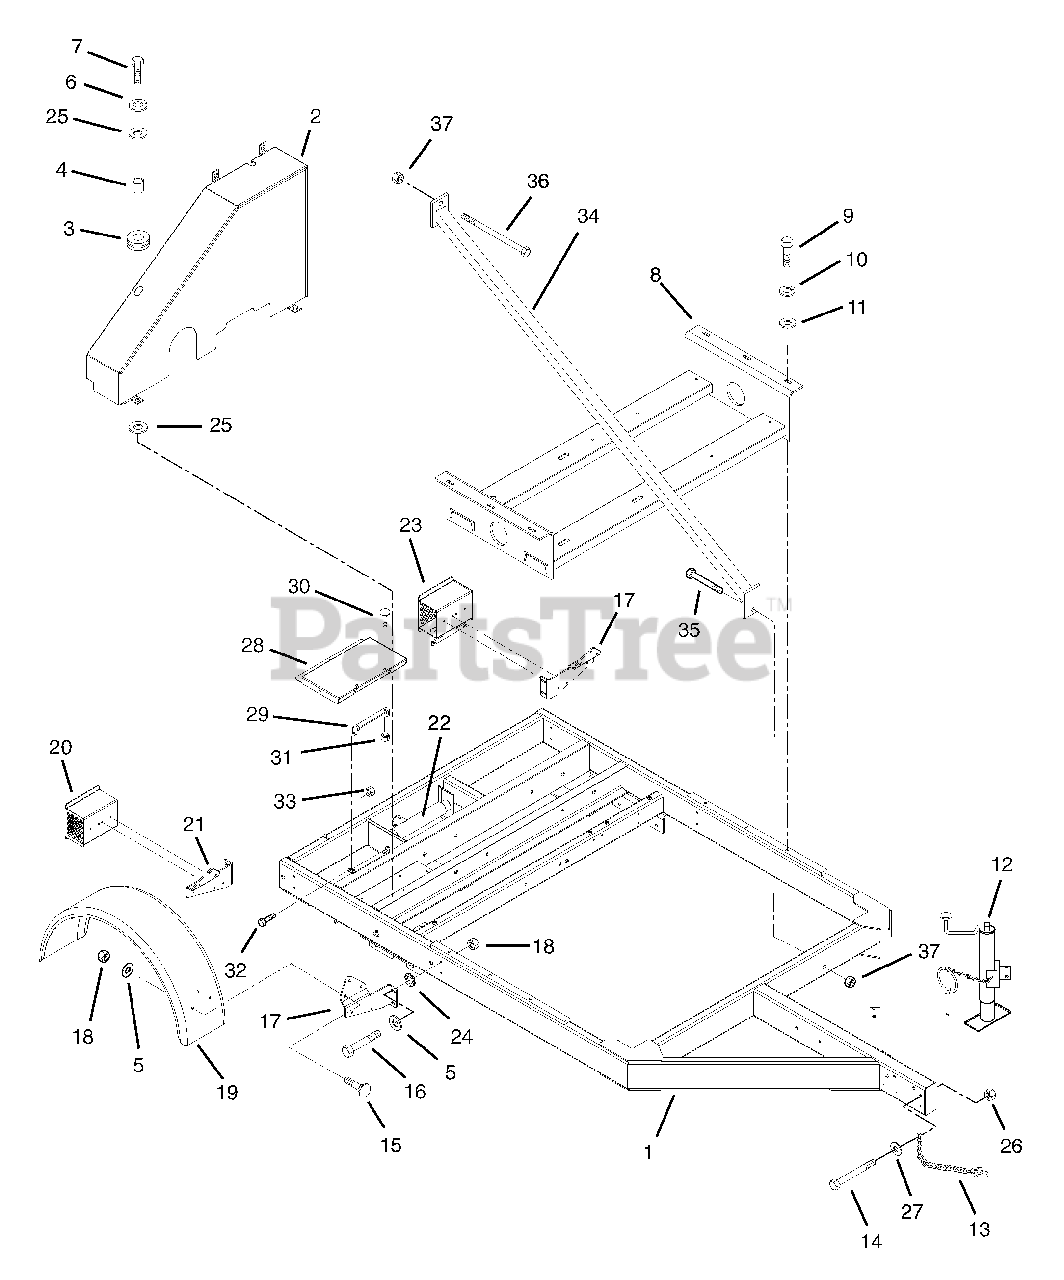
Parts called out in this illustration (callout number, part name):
1	Frame Weldment
2	Weldment-Belt Guard
3	Grommet .188 x .500
5	Washer-Flat-Steel .38 x .875 x .083
6	Washer-Lock .38 x .094
7	Bolt-Hex .38-16 x 1.25 Grade 5
8	Engine Base Weldment
9	Bolt-Hex .50-13 x 1.25 Grade 5
10	Washer-Lock .50 x .125
11	Washer-Flat-Steel .563 x 1.38 x .109
13	Safety Chain
14	Bolt-Hex .44-14 x 5.00 Grade 5
15	Bolt-Round Head Square Neck .31-18 x .75
16	Bolt-Hex .31-18 x 2.75 Grade 5
17	Fender Bracket-Left Hand
18	Nut-Locking-Center .31-18
19	Fender
20	Tail Light Bracket Weldment
21	Fender Bracket Right Hand
23	Left Hand Tail Light Bracket Weldment
24	Washer-Locking-External .326 x .599 x .031
25	Washer-Flat-Steel .39 x 1.5 x .125
26	Nut-Locking-Center .44-14
27	Washer-Flat-Steel .50 x 1.25 x .083
28	Tool Box Lid
29	Bracket -Chute
30	Bolt Round Head Square Neck .38-16 x .75
31	Nut-Locking-Center .38-16
32	Bolt-Hex .25-20 x .75 Grade 5
33	Nut-Locking-Center.25-20
34	Brace-Housing Weldment
35	Bolt-Hex .50-13 x 3.00 Grade 5
36	Bolt-Hex .50-13 x 9.00 grade 5
37	Nut-Locking-Center .50-13
